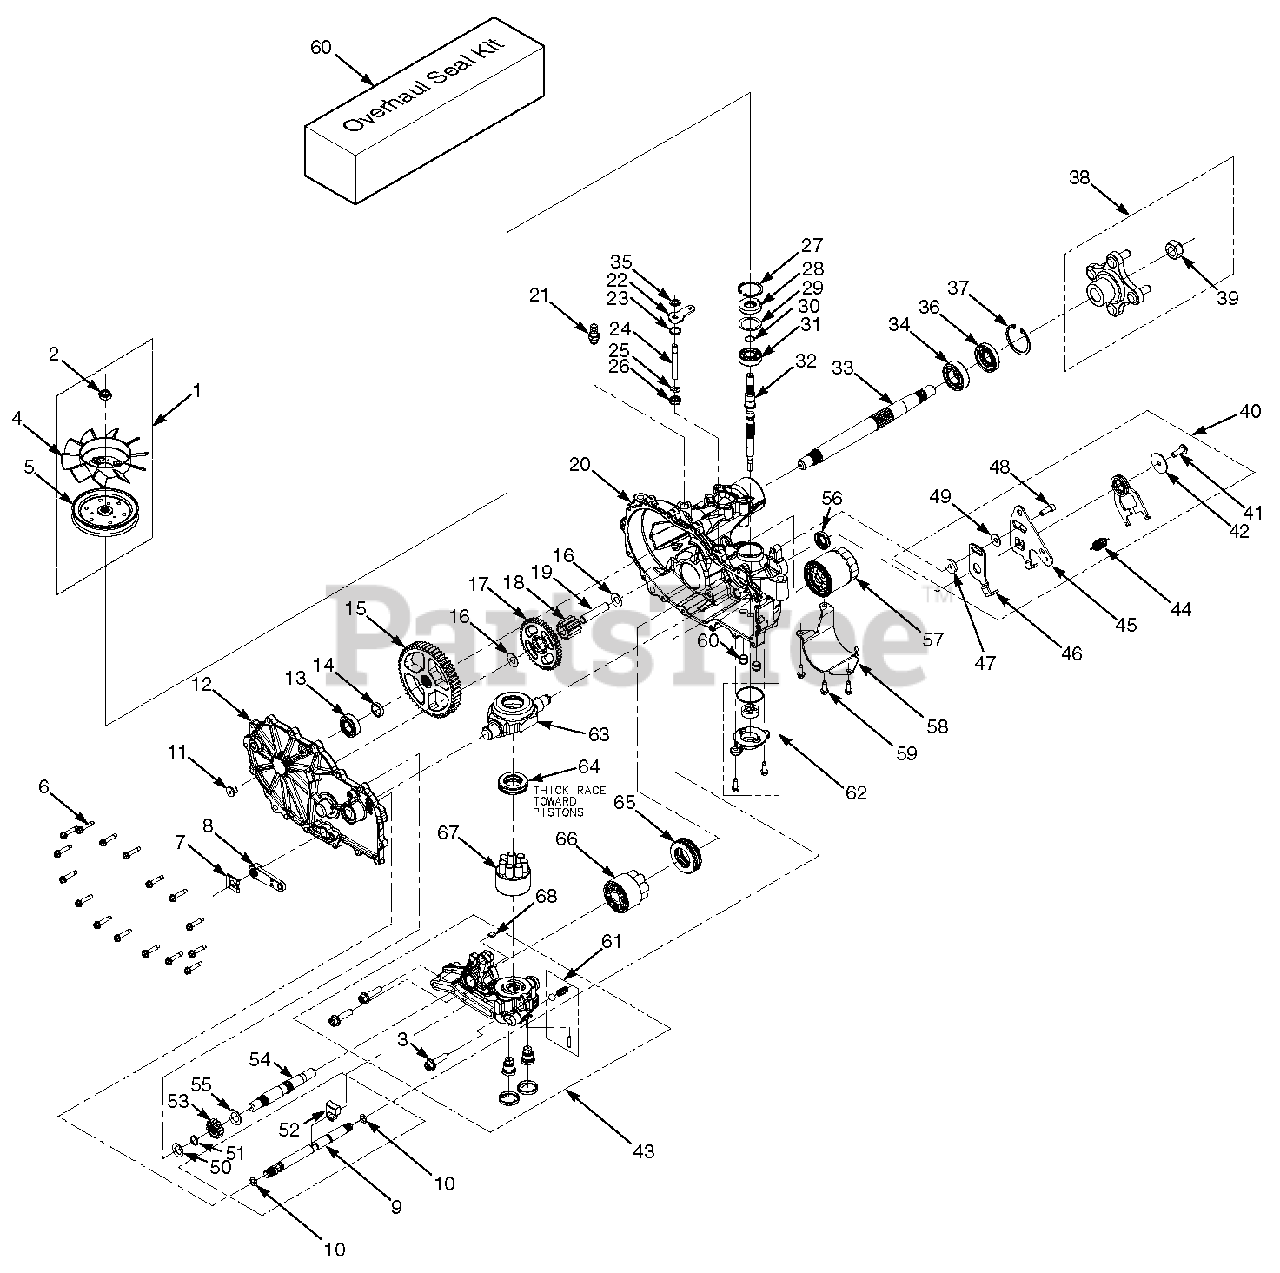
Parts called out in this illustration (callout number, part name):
1	Kit, Fan & Pulley
2	Nut, Hex Locking 1/2-20
3	Bolt, Hex Head 3/8-16 x 1-1/2" Patch
4	Fan, 7" Dai. (10 Blade)
5	Pulley, Cupped 4-1/2" Dia
5	Hub, Pulley
6	Bolt, Hex Head 1/4-20 x 1-11/4"
7	Clip, Retaining
8	Handle, Brake
9	Shaft, Brake
10	O-Ring
11	Plug, 9/16-18
12	Kit, Side Cover RH
12	Kit, Side Cover LH
13	Bearing, Ball .75 x 40 x 12
14	Spacer, .75 x 1.0 x .257
15	Gear, 54T
16	Washer, .5 x 1.0 x .03
17	Gear, 45T
18	Gear, 11T
19	Jackshaft Pin
20	Kit, Housing RH
20	Kit, Housing LH
21	Fitting
22	Arm, By-Pass
23	Ring, Retaining .750 Internal
24	Rod, By-Pass
25	Ring, .Retaining .375 External
26	Seal, Lip .375 x .75 x .25
27	Ring, Retaining 2.06 Internal
28	Seal, Lip 17 x 40 x 7
29	Washer, 1.23 x 1.56 x .04
30	Ring, Retaining Wire
31	Bearing, Ball 17 x 40 x 12 Open
32	Shaft, Input
33	Shaft Kit, Axle
34	Bearing, Ball 1.0 x 52 x 15 Open
35	Ring, Retainging .375 External
36	Seal, Lip 25 x 52 x 10 TC Gray
37	Ring, Retaining 2.06 Internal
38	Hub Kit
39	Nut, Hex Locking
40	Kit, RTN Assembly
41	Bolt, 5/16-24 x 1" Patch
42	Washer, .343 x 1.5 x .062
43	Kit, Center Section RH
43	Kit, Center Section LH
44	Spring
45	Arm, Control
46	Arm, Neutral RH
46	Arm, Neutral LH
47	Spacer, .320 x 1.005 x .179
48	Bolt, 5/16-24 x 1" Patch
49	Washer, .34 x .88 x .06
50	Washer, .63 x 1.0 x .05
51	Ring, Retaining
52	Pawl, Brake
53	Gear, 14T
54	Shaft, Motor
55	Washer, .72 x 1.16 x .04
56	Seal, Lip 18 x 32 x 7
57	Filter
58	Filter Guard
59	Bolt, 1/4-20 x 3/4"
60	Seal Kit
61	Kit, Charge Relief
62	Kit, Charge Pump
63	Trunnion Swashplate
64	Thrust Bearing
65	Thrust Bearing
66	Kit, Motor Cylinder Block
67	Kit, Cylinder Block
68	Plate, By-Pass
69	Kit, Charge Relief
